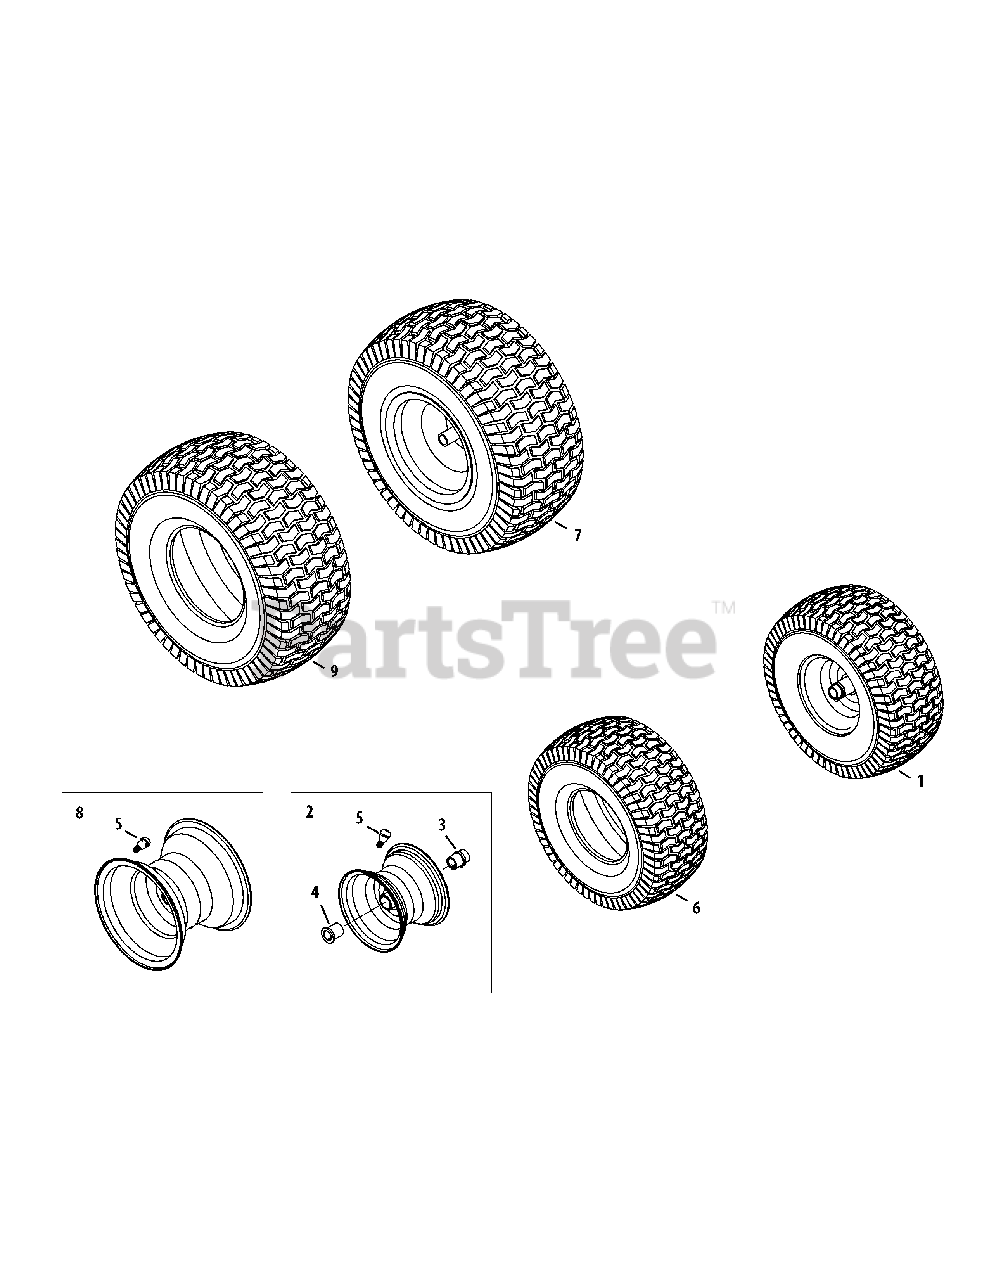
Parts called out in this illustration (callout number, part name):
1	Wheel Ass’y, Complete, 15 x 6 x 6
2	Rim Ass’y, 6.0 x 4.5, Flange Bearings
3	Bearing, Flange, .760 ID w/ Fitting
4	Bearing, Flange, .760 x 1.00 x 1.20
5	Valve, Tubeless Air
6	Tire, 15 x 6 x 6 Sq Shoulder
7	Wheel Assy, Complete, 20 x 10 x 8
8	Rim Ass’y, 8.0 x 7.0 x .750 ID
9	Tire, 20 x 10 x 8 Sq Shoulder
